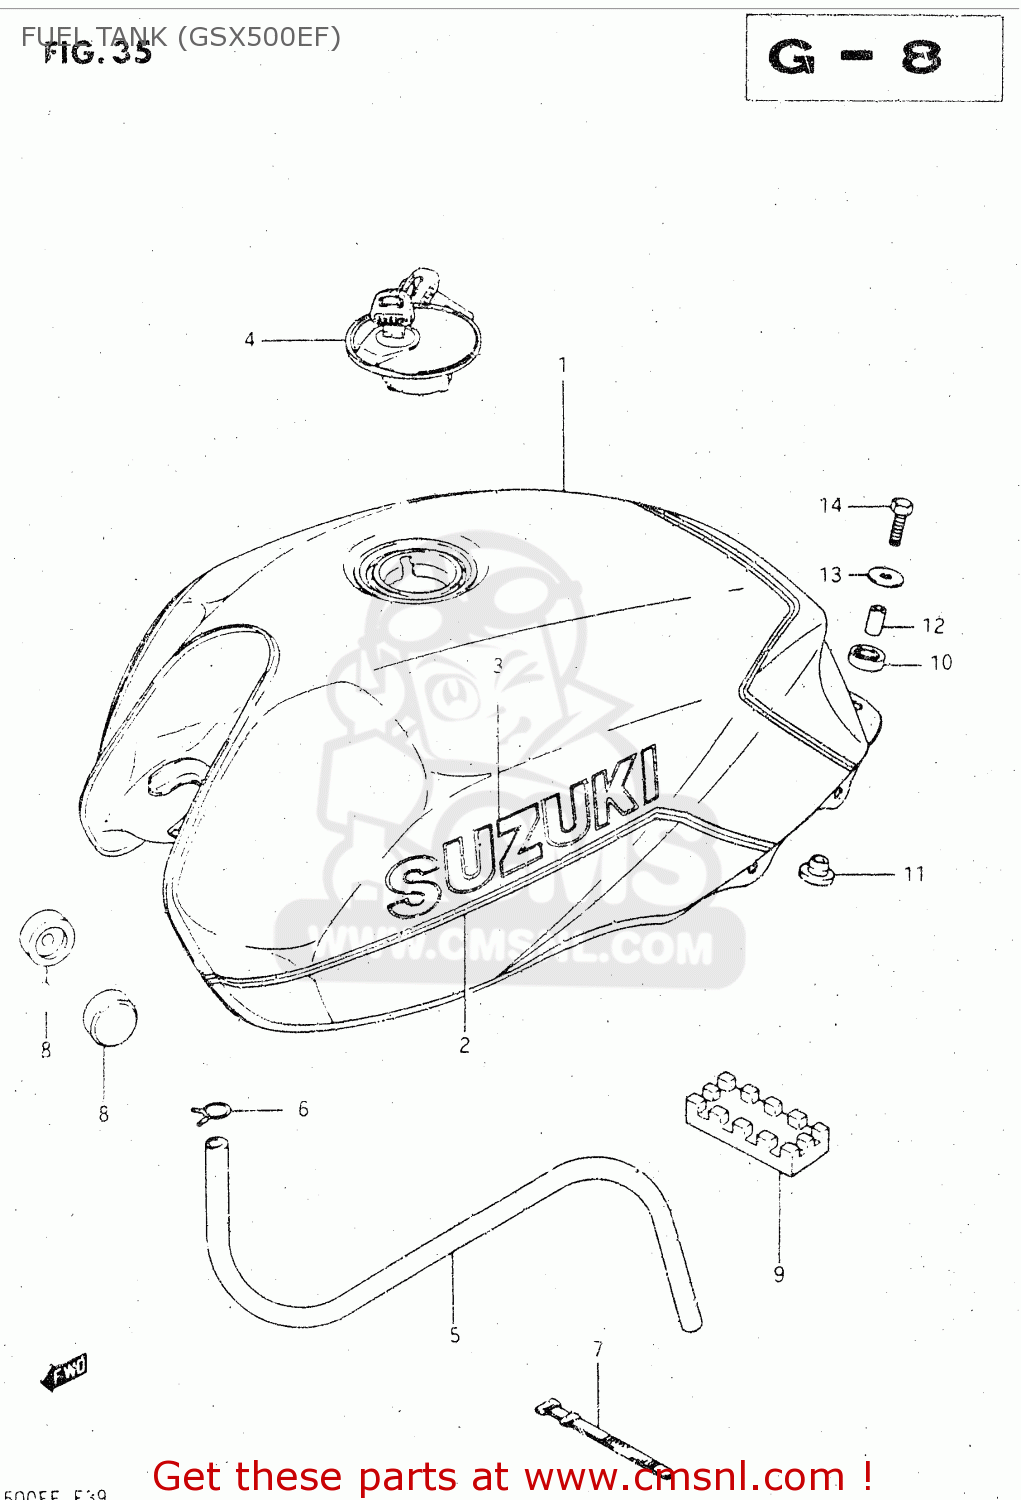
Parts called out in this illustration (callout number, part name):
1	TANK ASSEMBLY,FUEL
2	TAPE SET,FUEL TANK
3	EMBLEM
4	CAP ASSY,FUEL TANK
5	HOSE,FUEL
6	CLIP
7	CLAMP(L:187)
8	CUSHION
9	CUSHION,FUEL TANK
10	CUSHION
11	CUSHION
12	SPACER (6.4X9X20)
13	WASHER (6.5X24X1.6)
14	BOLT
